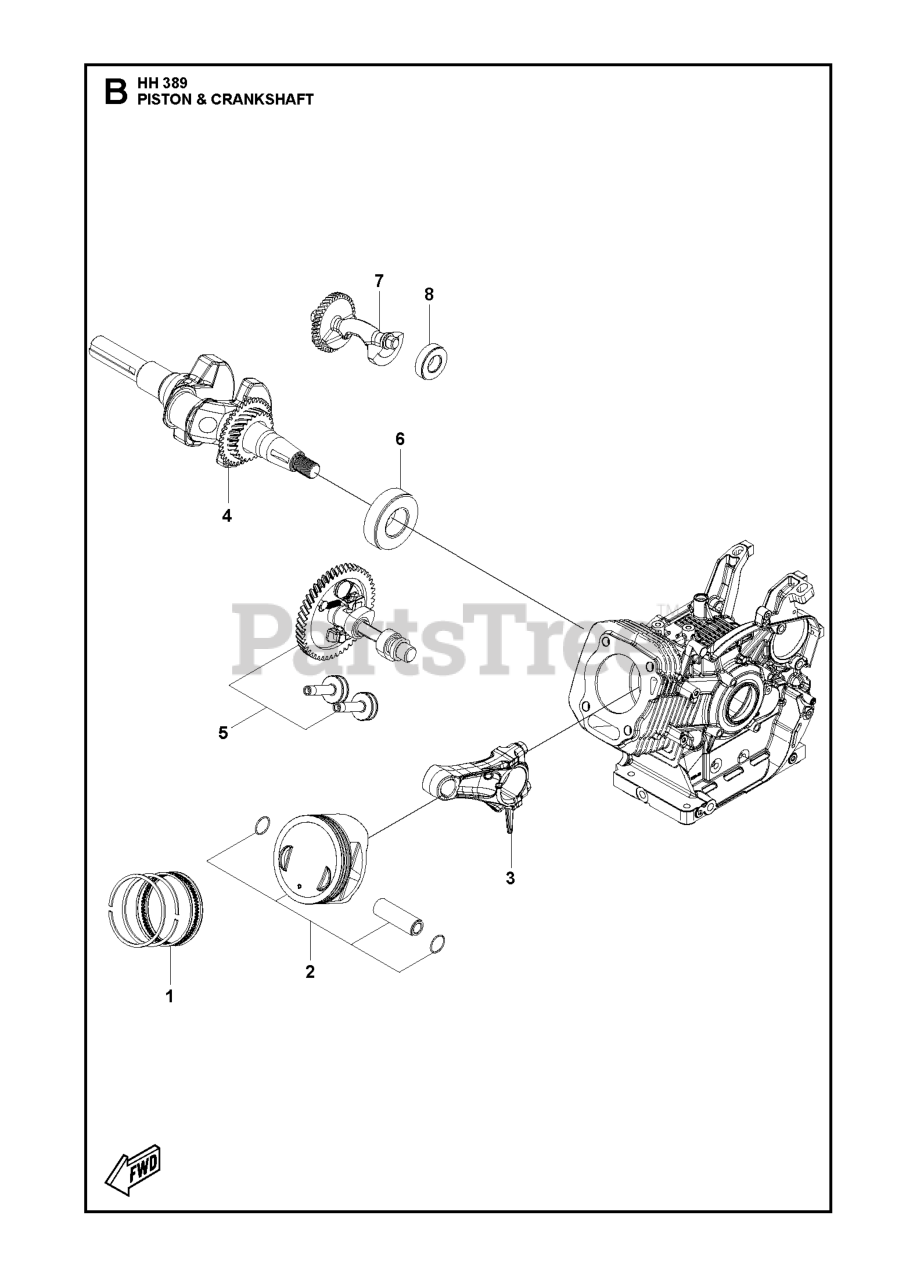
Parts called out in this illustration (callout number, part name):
1	PISTON RING SET
2	PISTON ASSY
3	CONNECTING ROD
4	CRANKSHAFT
5	CAMSHAFT KIT
6	BALL BEARING
7	SHAFT BALANCING SHAFT
8	BALL BEARING
